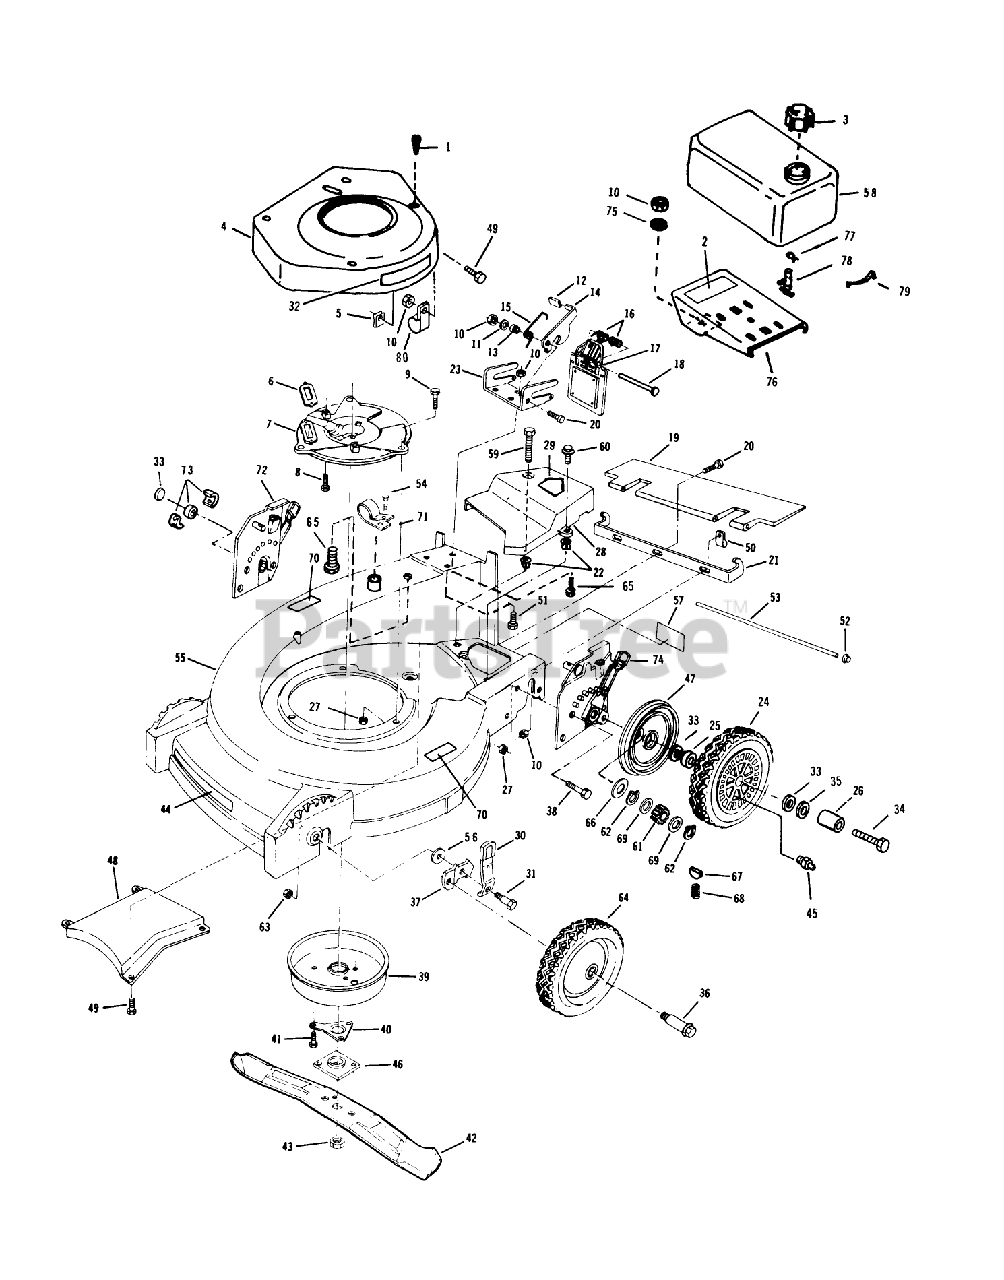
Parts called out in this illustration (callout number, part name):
1	SCREW - SELF TAPPING
3	FUEL CAP & INSERT
5	PUSHNUT F
7	M/PLATE
8	SCREW V
9	SCREW-HH
10	LOCKNUT E
12	KNOB (S&R)
15	SPRING
16	SPRING ASOC
18	ROD (RB&W)
19	T/SHIELD SM&P
27	NUT-LOCK F
30	SPRING ARM ASM
31	BOLT
32	MANUAL
33	WASHER
35	SPACER
36	BOLT-SHOULDER
39	MUFFLER COVER F
40	SUPPORT F
41	SCREW
43	NUT-BLADE
45	FITTING LINCOLN
46	PLATE AND COLLAR ASM
48	BAFFLE CHUTE PL
51	SCREW
54	SCREW LAWRENCE
56	WASHER
60	SCREW
61	PINION BROCKWAY
62	RET RING
63	LOCKNUT
65	SCREW HEX WASHER
66	THRUST WASHER
67	KEY
68	SPRING
69	SPACER/GR ALGHNY
73	REAR AXLE BEARING
75	WASHER
76	BRACKET - TANK
77	CLAMP - HOSE S
78	VALVE&SCREEN SM
79	SPRING
